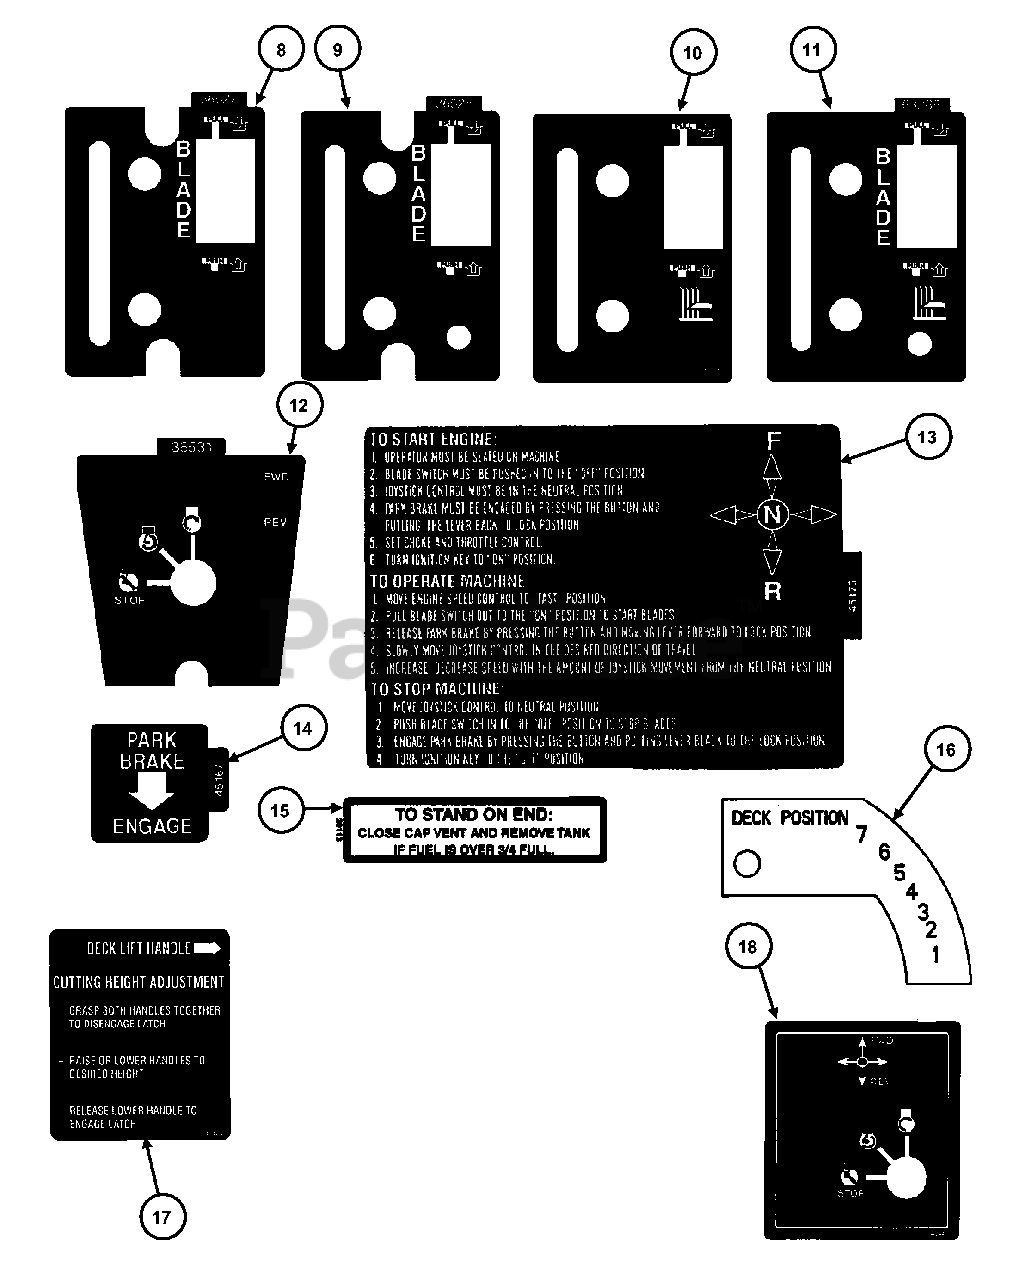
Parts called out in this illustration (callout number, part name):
8	DECAL, Throttle Control
9	DECAL, Throttle Control
10	DECAL, Throttle Control
11	DECAL, Throttle Control Choke
12	DECAL, Ignition Switch
13	DECAL, Operation
14	DECAL, Parking Brake
15	DECAL, Caution Fuel (English)
16	DECAL, Deck Position
17	DECAL, Deck Height
18	DECAL, Ignition Switch LC HOZ
